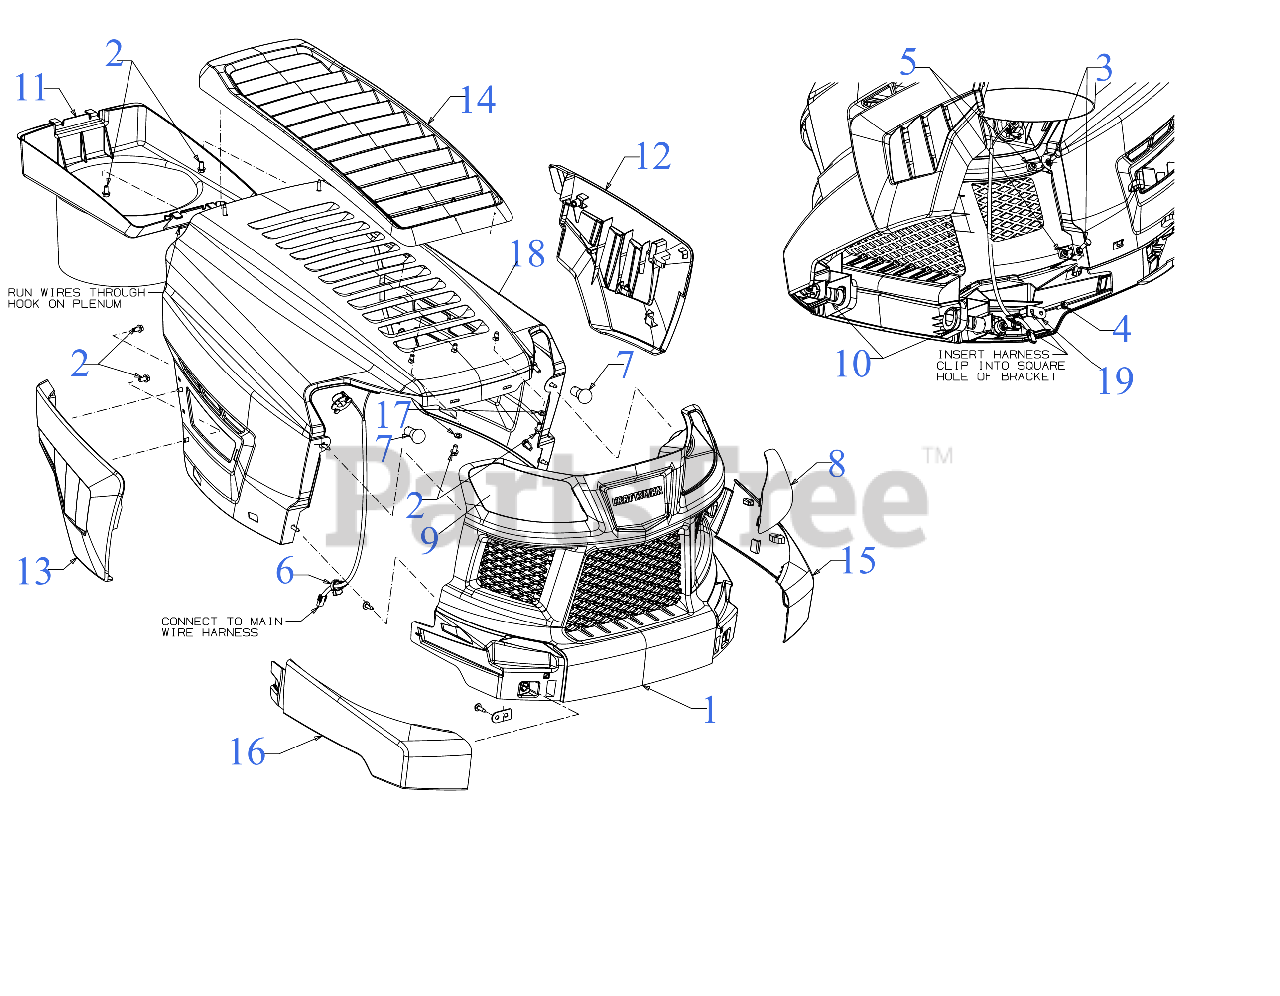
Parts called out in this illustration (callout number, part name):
1	GRILLE
2	HEX SCREW 1/4-15 x .50
3	SCREW 1/4-20 x .62 SPEC GR5
4	SCREW 1/4-10 x .750
5	SQUARE NUT 1/4-20
6	HEADLIGHT HARNESS
7	MINIATURE LAMP-12V #1156
8	GRILLE LENS (LH)
9	GRILLE LENS (RH)
10	HOOD PIVOT PIN
11	HOOD PLENUM
12	HOOD SIDE COVER (LH)
13	HOOD SIDE COVER (RH)
14	HOOD SCOOP
14	SCREW 1/4-10 x .750
15	GRILLE PANEL (LH) (LIBERTY RED)
16	GRILLE PANEL (RH) (LIBERTY RED)
17	FLAT WASHER
19	HARNESS CLIP BRACKET
